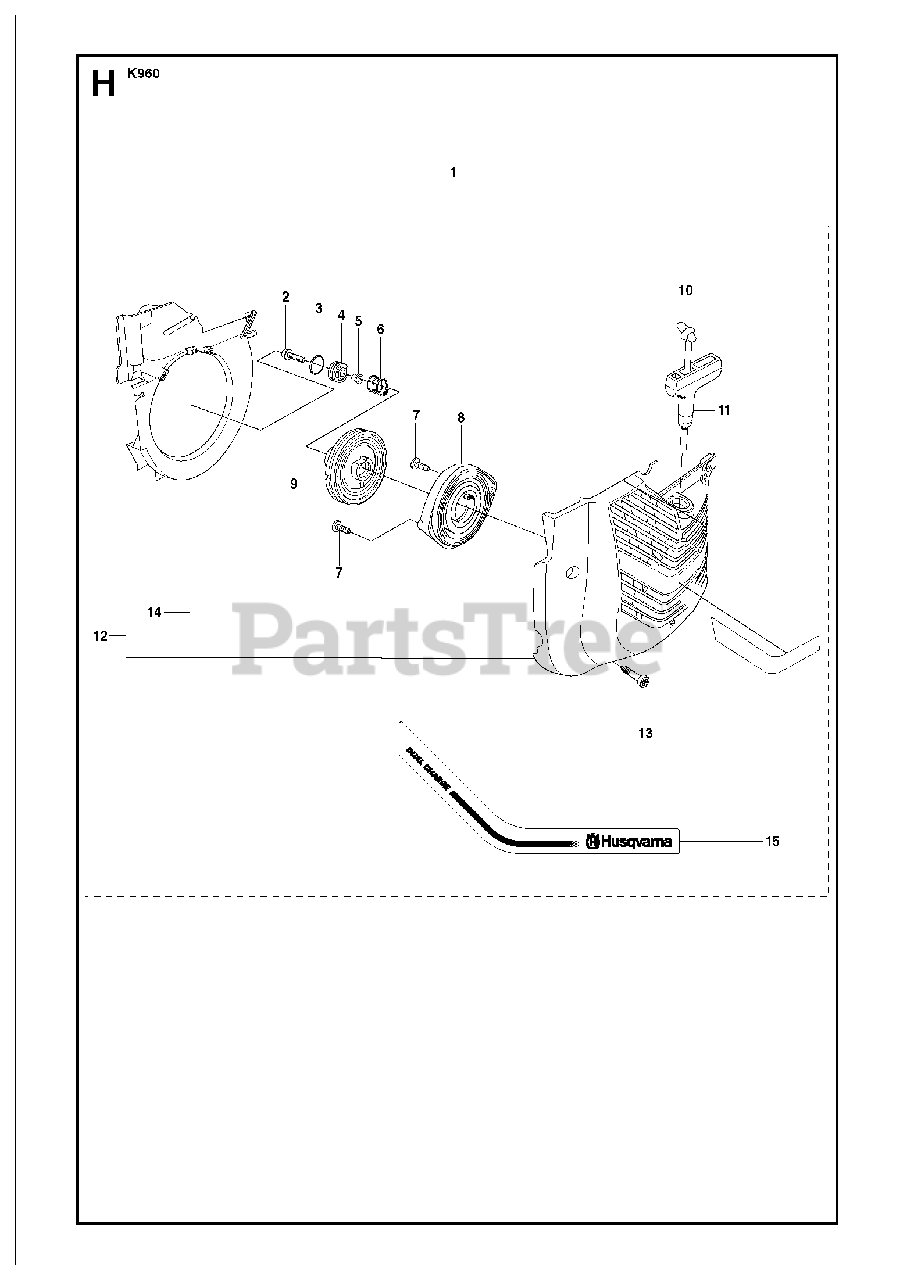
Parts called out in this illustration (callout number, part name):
1	STARTERIncl. 2 - 15
2	SCREW IHSCT
4	GROMMET
5	SPACING SLEEVE
6	COMPRESSION SPRING
7	SCREW CCRPANT
8	RECOIL SPRING
9	STARTER PULLEY
10	STARTER CORD50 m Coil
11	STARTER HANDLE
12	STARTER COVERIncl. 14
13	SCREW ITXSCM
14	AIR CONDUCTOR
